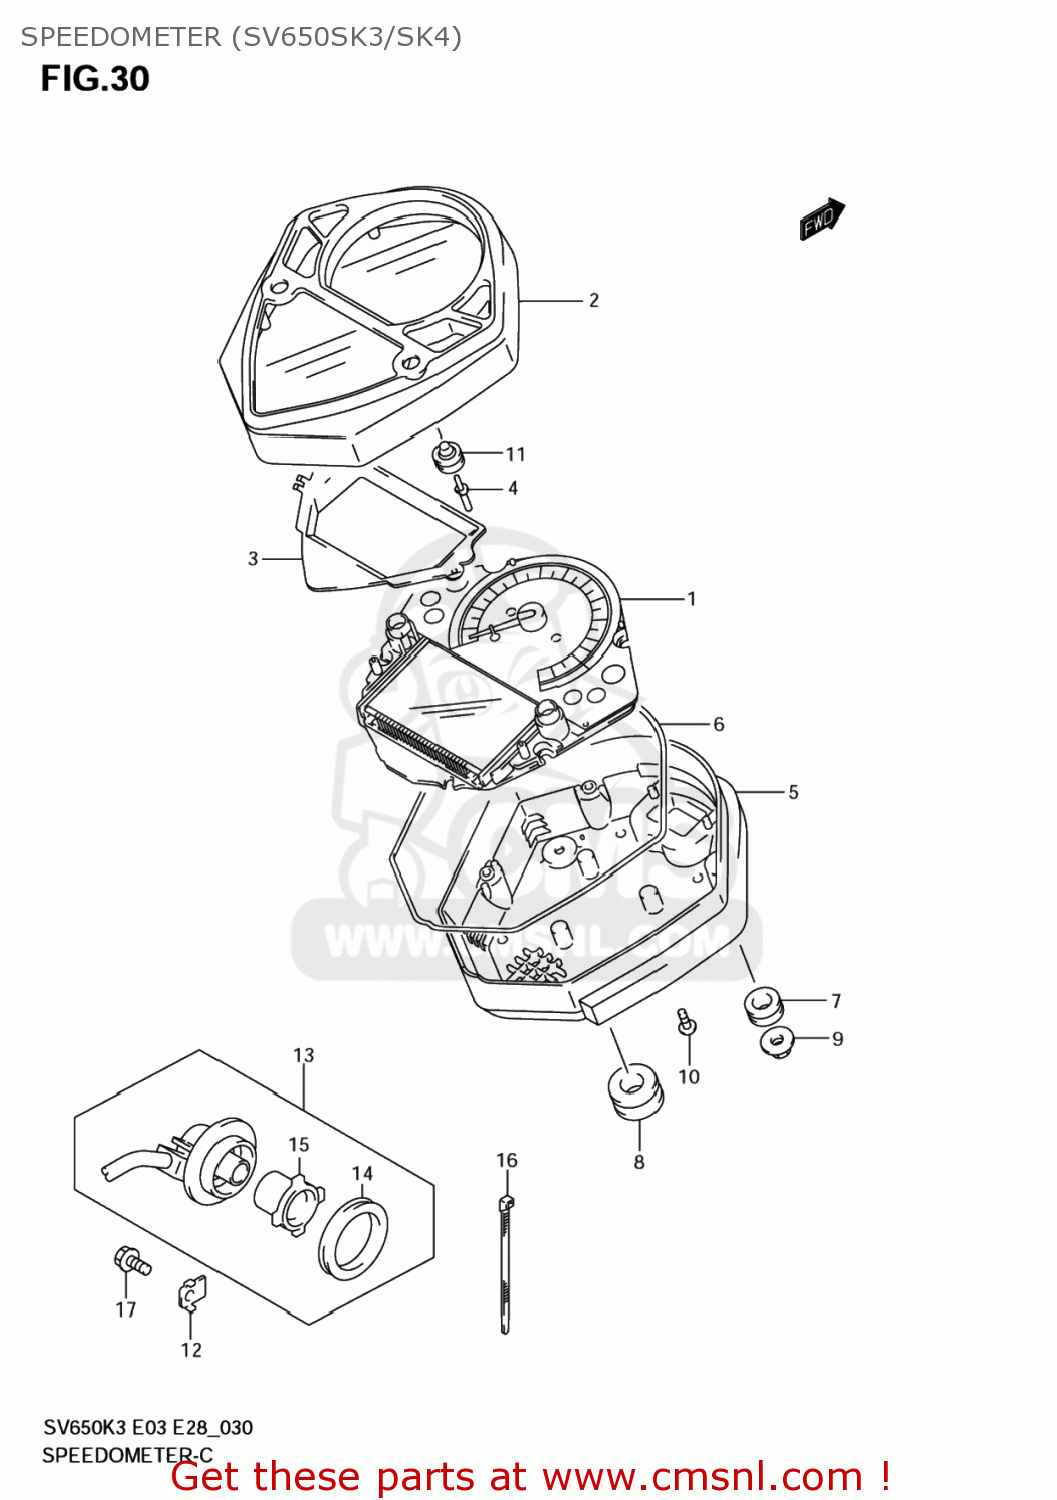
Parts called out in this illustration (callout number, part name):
1	SPEEDOMETER
2	CASE,SPEEDOMETER UPR
3	PLATE,SPEEDOMETER
4	KNOB,SPEEDOMETER
5	CASE,SPEEDOMETER LWR
6	GASKET,METER CASE (NAS)
7	CUSHION
8	CUSHION
9	NUT
10	SCREW,SPEEDOMETER
11	COVER,SPEEDOMETER KNOB
12	GUIDE,SENSOR LEAD
13	SENSOR,SPEED
14	SEAL,OIL(44X55X6)
15	ROTOR,SPEEDOMETER
16	CLAMP(L:145)
17	BOLT
